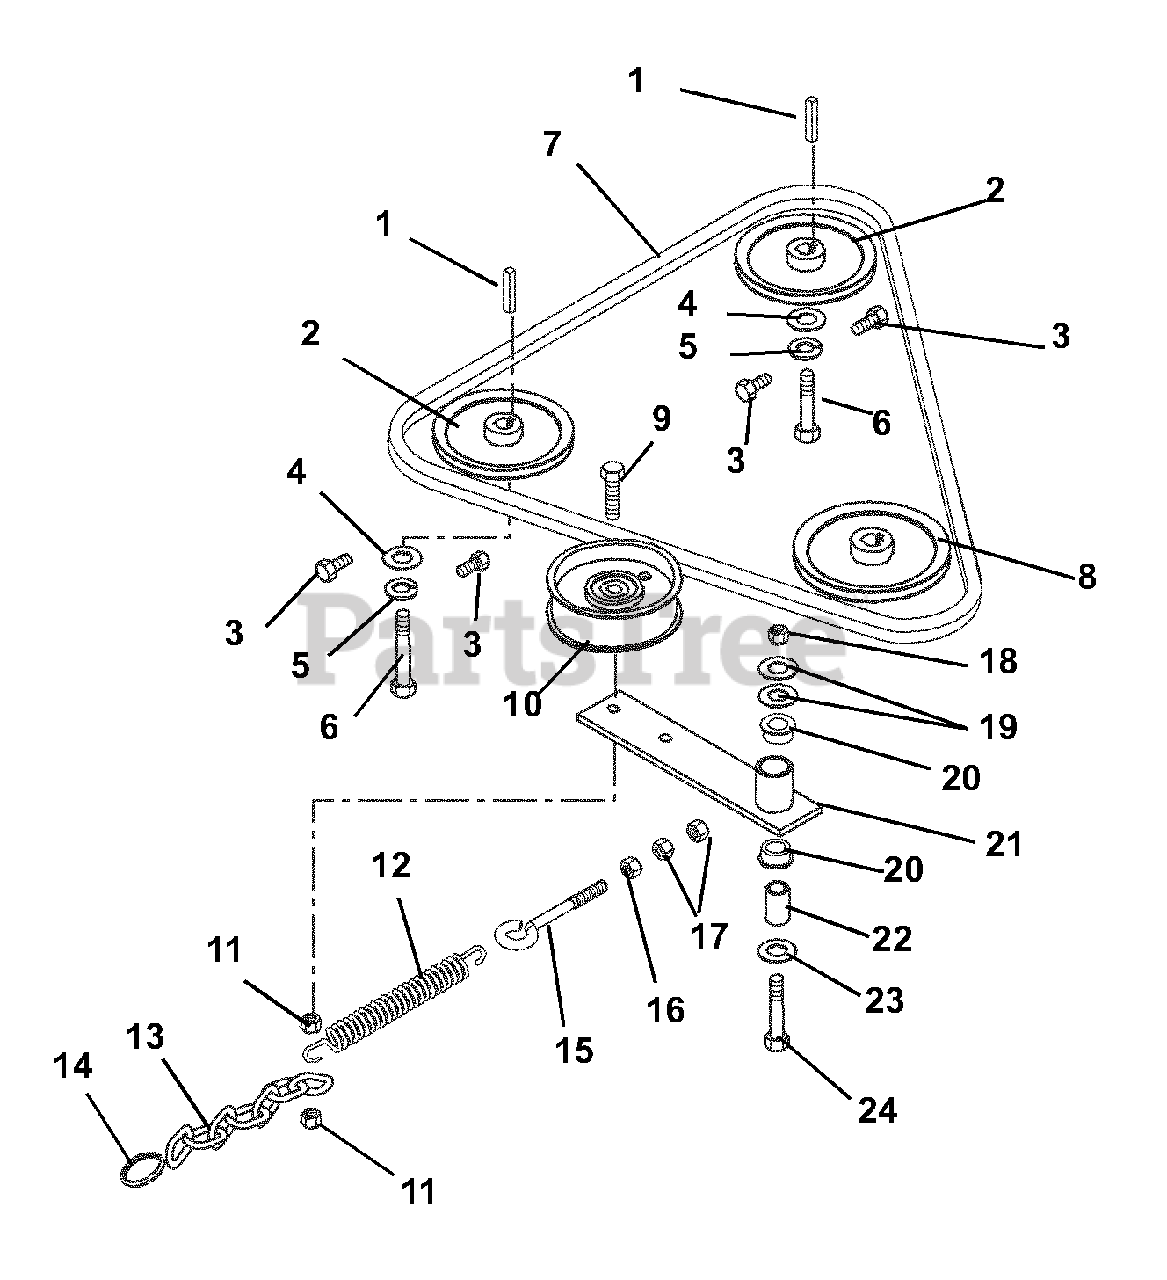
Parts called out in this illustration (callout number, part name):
1	Key, Straight 5MM x 25MM x 5MM
2	Sheave 4.0 x .199
3	Bolt, Hex .25-20 x .50 Grade 5
4	Washer, Flat Steel .281 x 1.25 x .048
5	Washer, Locking .25 x .062 Regular
6	Bolt, Hex M6 x 1.0 x 12
7	Belt, Hydro Ground Drive
9	Bolt, Hex .38-16 x 2.00 Grade 5
10	Idler, Pulley Flat 3.25 x .625
11	Nut, Locking Jam Center .375-16
12	Spring, Extension
13	Chain, Link
14	Ring, Split .1 x 2
15	Bolt, Eye .375-16 x 2.50
16	Nut, Hex .38-16
17	Nut, Locking Nylon .38-16
18	Nut, Locking Nylon .50-13
19	Washer, Flat Steel .531 x 1.06 x .095
20	Bushing, Flange Nylon .762 x 1.00 x .58 x 1.48
21	Weldment,Ground Drive Idler
22	Bushing,Spacer .56 x .745 x 2.04 Steel
23	Washer, Flat Steel .531 x 1.06 x .095
24	Bolt, Hex .50-13 x 3.25 Grade 5
